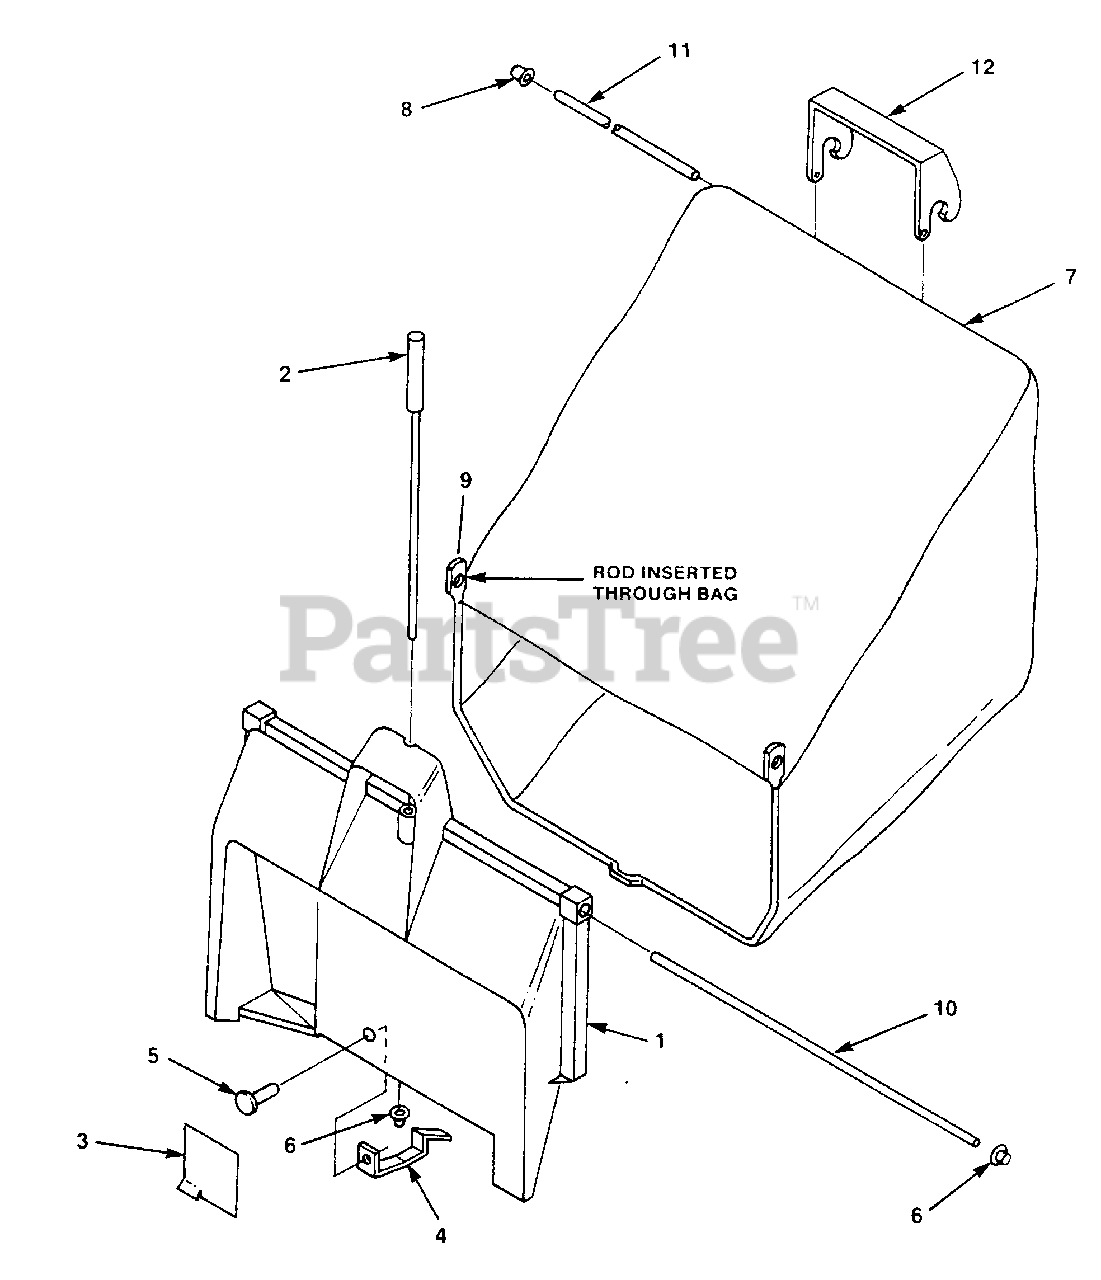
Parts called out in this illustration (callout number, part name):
1	ADAPTOR- Bag
2	ROD- Latch release
3	DEFLECTOR
5	RIVET- Pop 5/32 x 3/8
7	CATCHER- Grass
9	ROD- Bag Support
10	ROD- Bag hinge
11	ROD- Upper bag
12	HANDLE- Upper bag
